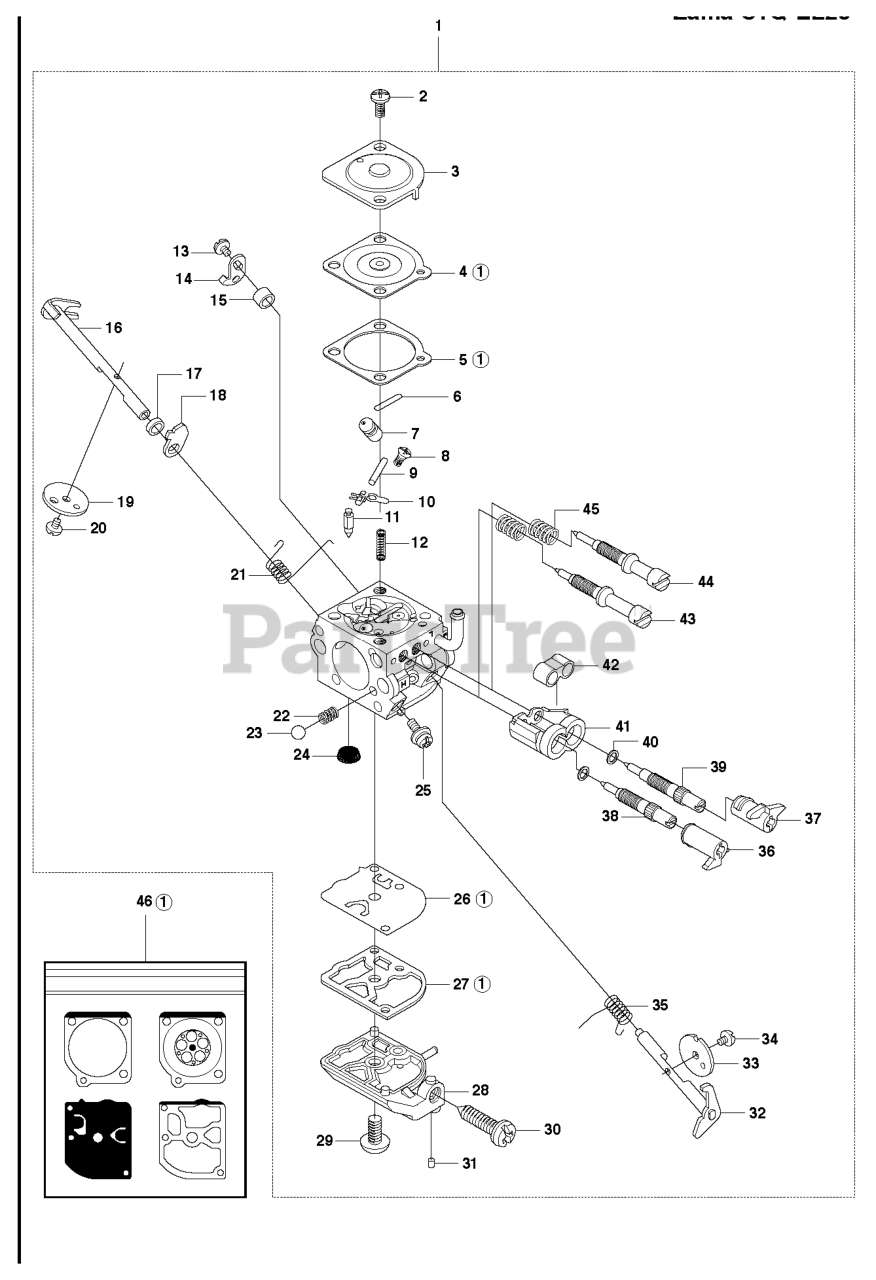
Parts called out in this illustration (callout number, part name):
1	CARBURETOR
4	METERING DIAPHRAGM
5	GASKET METERING SIDE
9	PIN RETAINING SCREW
11	INLET NEEDLE
12	SPRING
16	CHOKE SHAFT
19	DISC
26	PUMP DIAPHRAGM
27	GASKET
32	THROTTLE SHAFT
33	THROTTLE FLAP
36	LIMITER CAP
37	LIMITER CAP
38	NEEDLE HIGH SPEED
39	NEEDLE LOW SPEED
40	WASHER
41	SLEEVE
42	SLEEVE
43	SCREW
44	IDLE SCREW
45	SPRING
46	GASKET SET
